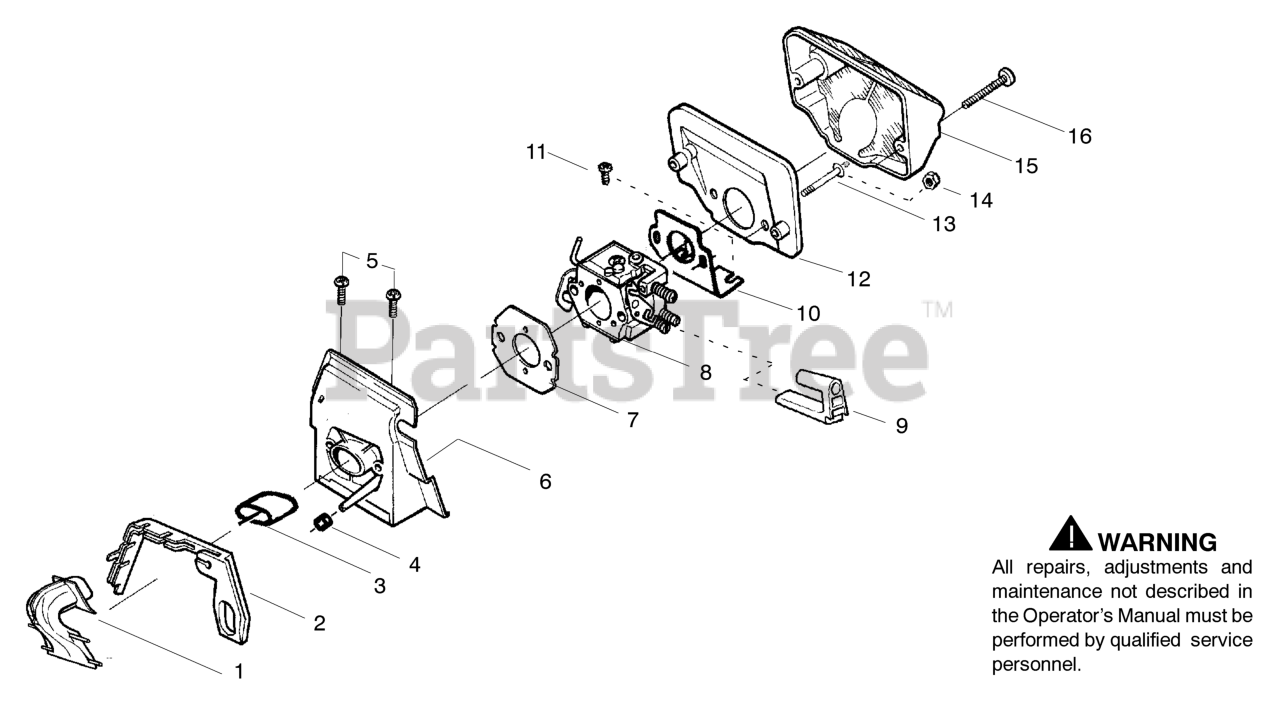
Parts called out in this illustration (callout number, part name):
1	INTAKE HORN
2	TURBO CLEAN SEAL
3	INTAKE PIPE
4	IMPULSE PIPE
6	CARB ADAPTOR
7	GSKT,CARB 36/41
8	CARBURETOR W-29
12	AIR FILTER (BOTTOM)
13	STUD-CARBURETOR
15	AIR FILTER
